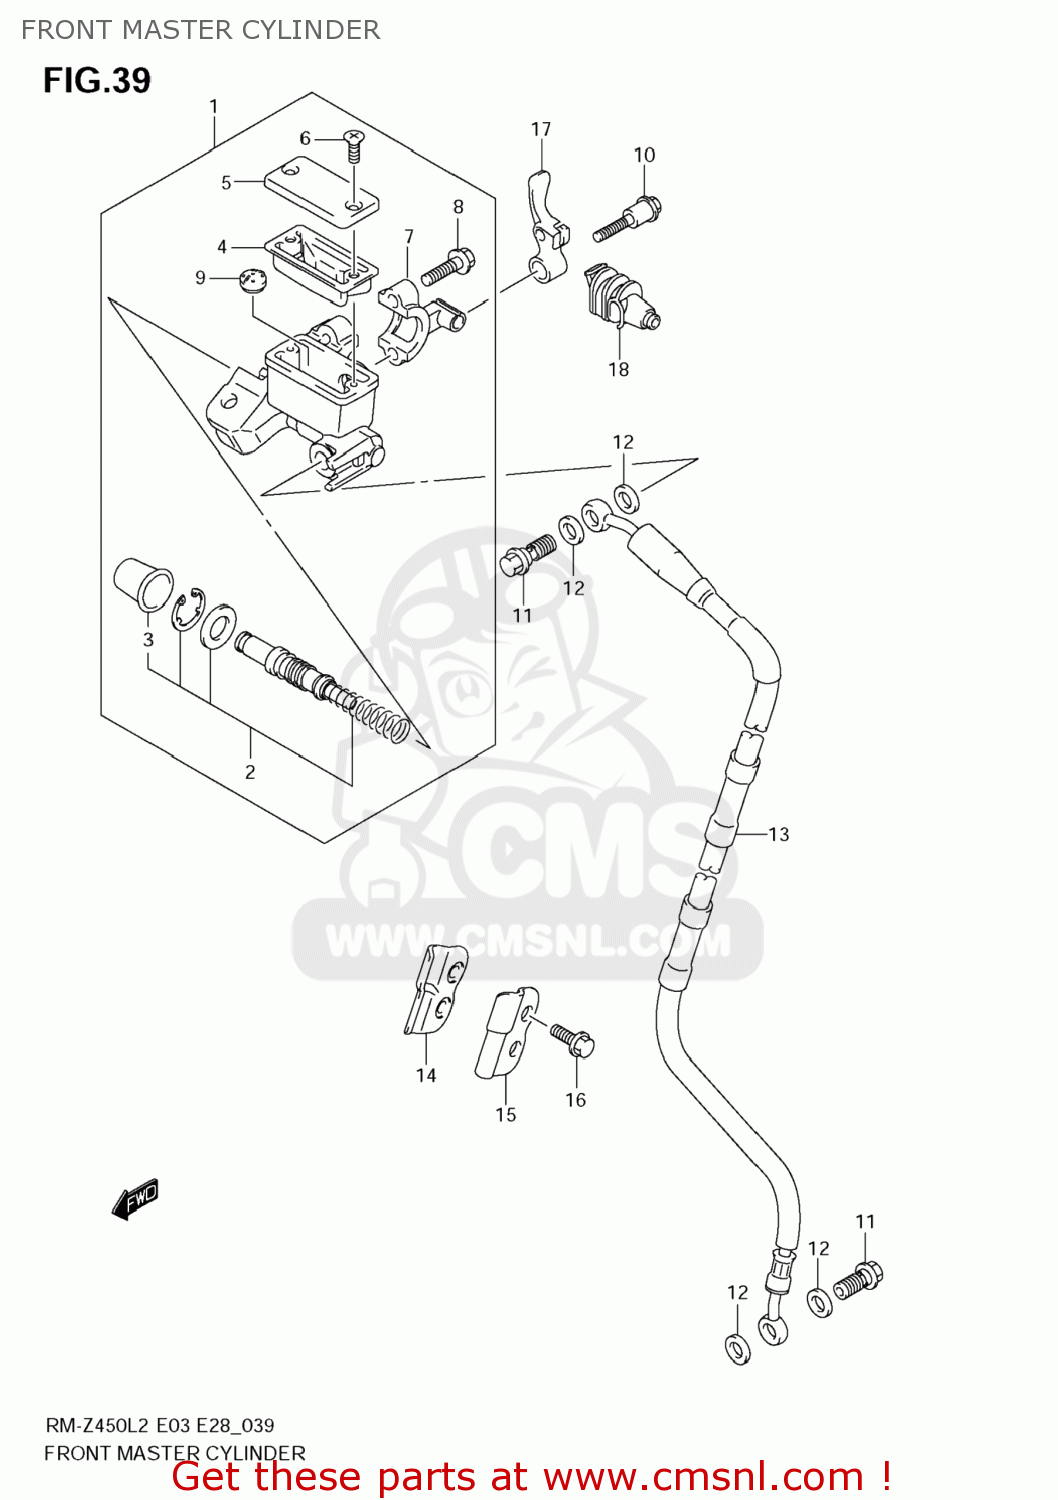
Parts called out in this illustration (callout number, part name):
1	CYLINDER ASSY,FR MASTER
2	PISTON & CUP SET
3	BOOT
4	DIAPHRAGM
5	CAP
6	SCREW
7	HOLDER
8	BOLT
9	SEPARATOR
10	BOLT,MASTER CYLINDER HOLDER
11	BOLT UNION
12	WASHER(10X15X1.5)
13	HOSE,FR BRAKE
14	CLAMP,FR BRAKE HOSE
15	CLAMP,FR BRAKE HOSE
16	BOLT(6X16)
17	LEVER,MASTER CYLINDER HOLDER
18	COVER,MASTER CYL HOLDER LEVER
